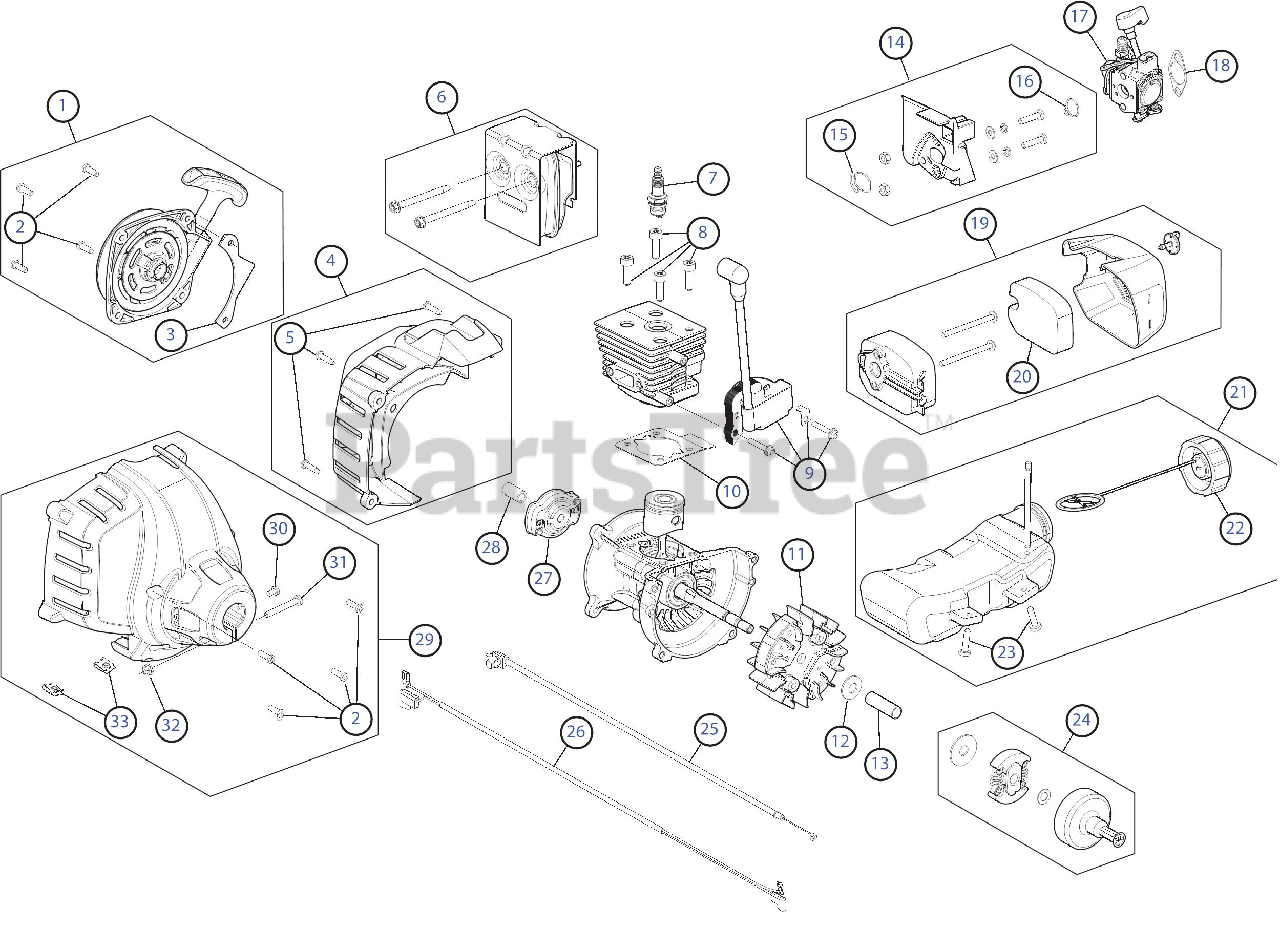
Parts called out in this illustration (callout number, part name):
1	Starter Assembly (Incl. 2 & 3)
2	Starter Screw
3	Starter Assembly Guard (Incl. 2)
4	Rear Engine Cover (Incl. 5)
5	Cover Screw
6	Muffler Assembly
7	Spark Plug
8	Cylinder Bolt
9	Module Assembly
10	Cylinder Gasket
11	Flywheel Assembly
14	Insulator Assembly (Incl. 15 & 16)
15	Insulator O-Ring
16	Carburetor O-Ring
17	Carburetor
18	Carburetor Gasket
19	Air Cleaner Assembly (Incl. 20)
20	Air Cleaner Filter
21	Fuel Tank Assembly (Incl. 22 & 23)
22	Fuel Tank Cap
23	Fuel Tank Screw
24	Clutch Assembly
25	Throttle Cable
26	Lead Wires
27	Pawl Assembly
29	Clutch Cover Assembly (Incl. 2, 30 - 33)
30	Anti-rotation Screw
31	Clamp Screw
32	Clamp Nut
33	U-shaped Nut
